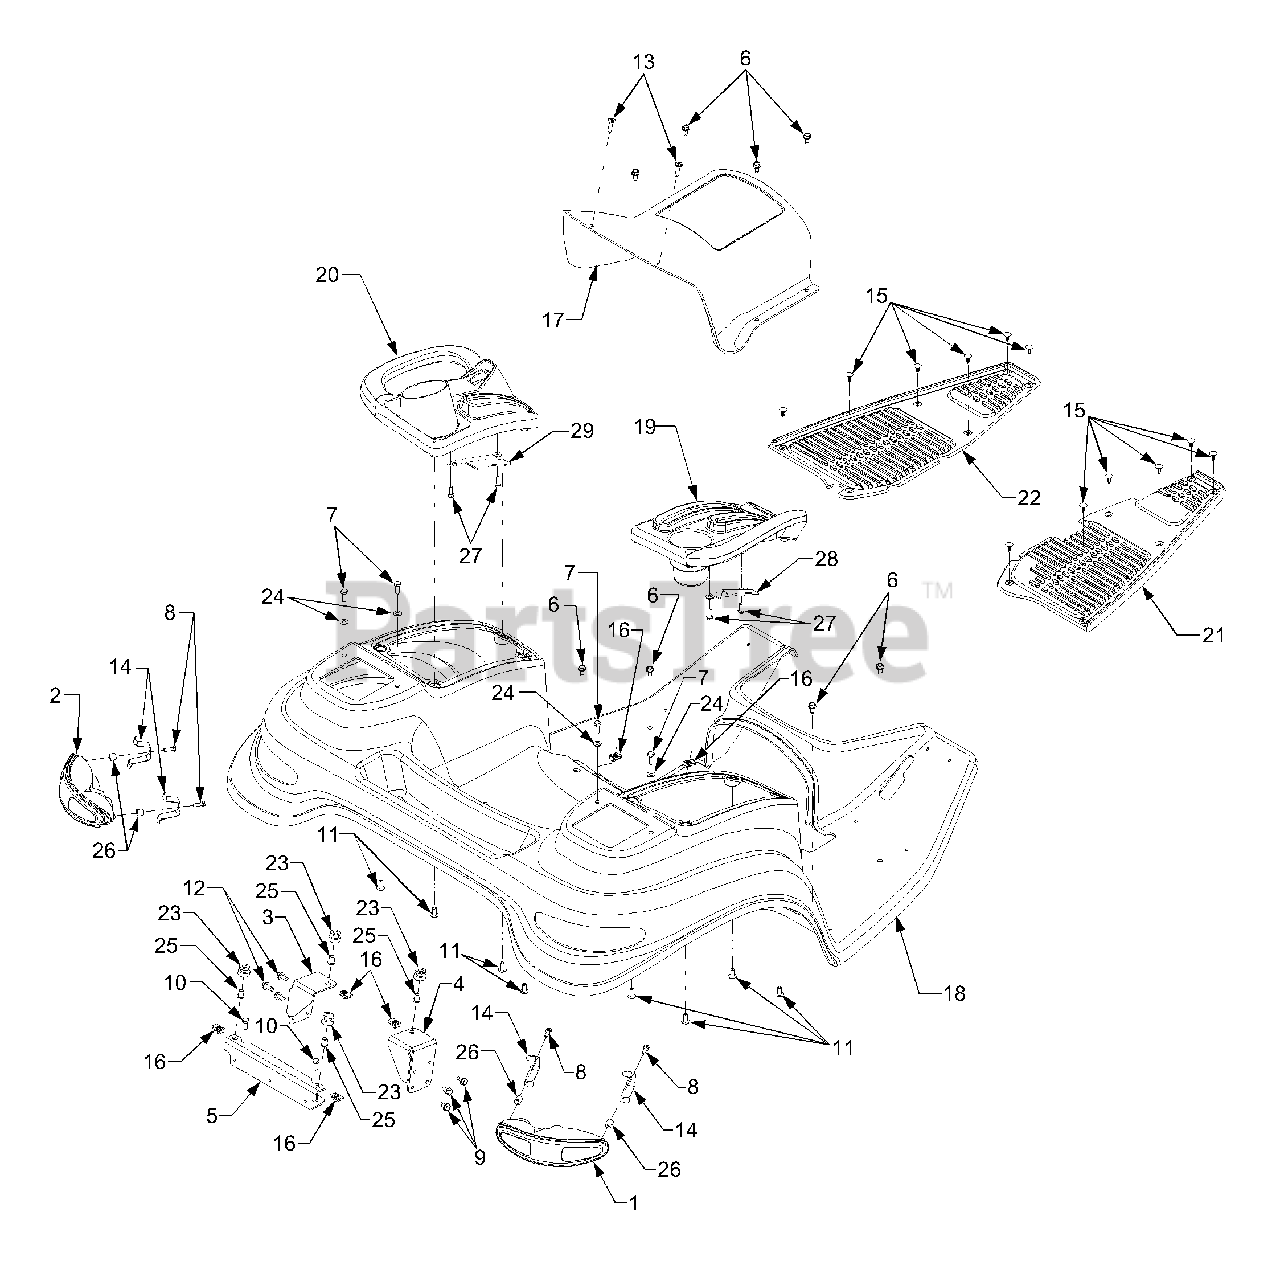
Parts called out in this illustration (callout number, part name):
1	Light Assembly, Rear RH
2	Light Assembly, Rear RH
3	Bracket, Seat Mtg. LH
4	Bracket, Seat Mtg. RH
5	Bracket, Rear Seat Support
6	Screw, Hex Wash Hd. Tapp 5/16-18 x .625
7	Screw, Hex Cap 5/16-18 x .875 GR5
8	Screw, Hex Cap 1/4-20 x .875 GR5
9	Screw, Hex Wash Hd. Tapp 5/16-18 x .625
10	Screw, Hex Cap 5/16-18 x .75 GR5
11	Screw, Truss Phillips Hd. 5/16-14 x .75
12	Screw, Hex Wash Hd. Tapp 5/16-18 x .75
13	Screw, Pan Hd. 5/16-18 x 1.0
14	Clip, Tail Light
15	Clip, Ratchet Fastener
16	Speed Nut, 'U' Type, 5/16-18
17	Cover, Fender
19	Cover, Fender, RH
20	Cover, Fender, LH
21	Pad, Floor, RH
22	Pad, Floor, LH
23	Grommet, .4375 ID x .75
24	Washer, Flat, .345 x 1.0 x .100
25	Spacer, Flange, .3125 x .4375 x .625
26	Spacer, .258 x .5 x .5
27	Screw, Hex Wash Hd Tapp, 1/4-15 x .75
